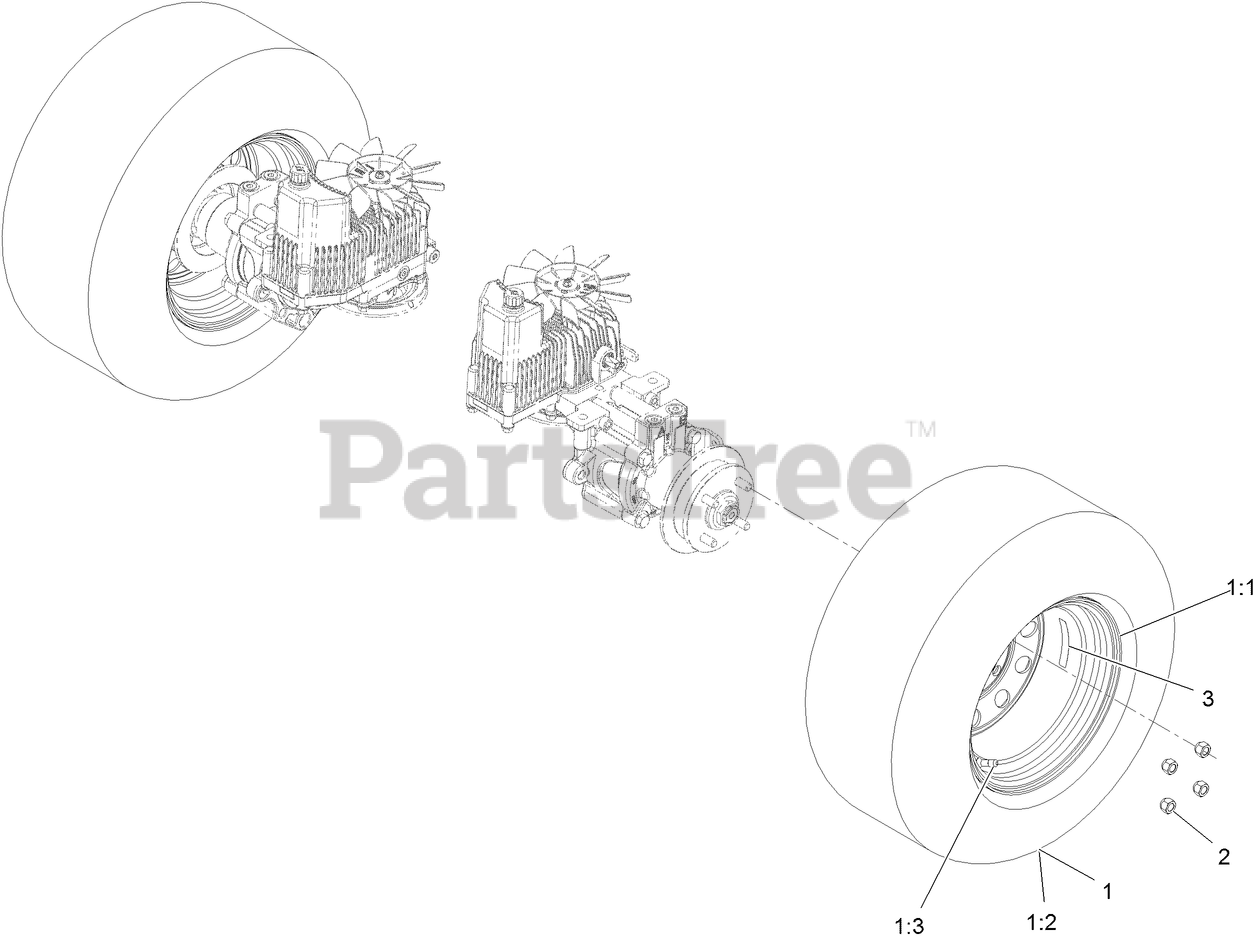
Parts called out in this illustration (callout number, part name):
1	WHEEL AND TIRE ASM
1:3	Stem-Valve
2	NUT-LUG
3	Decal-Wheel Hub
